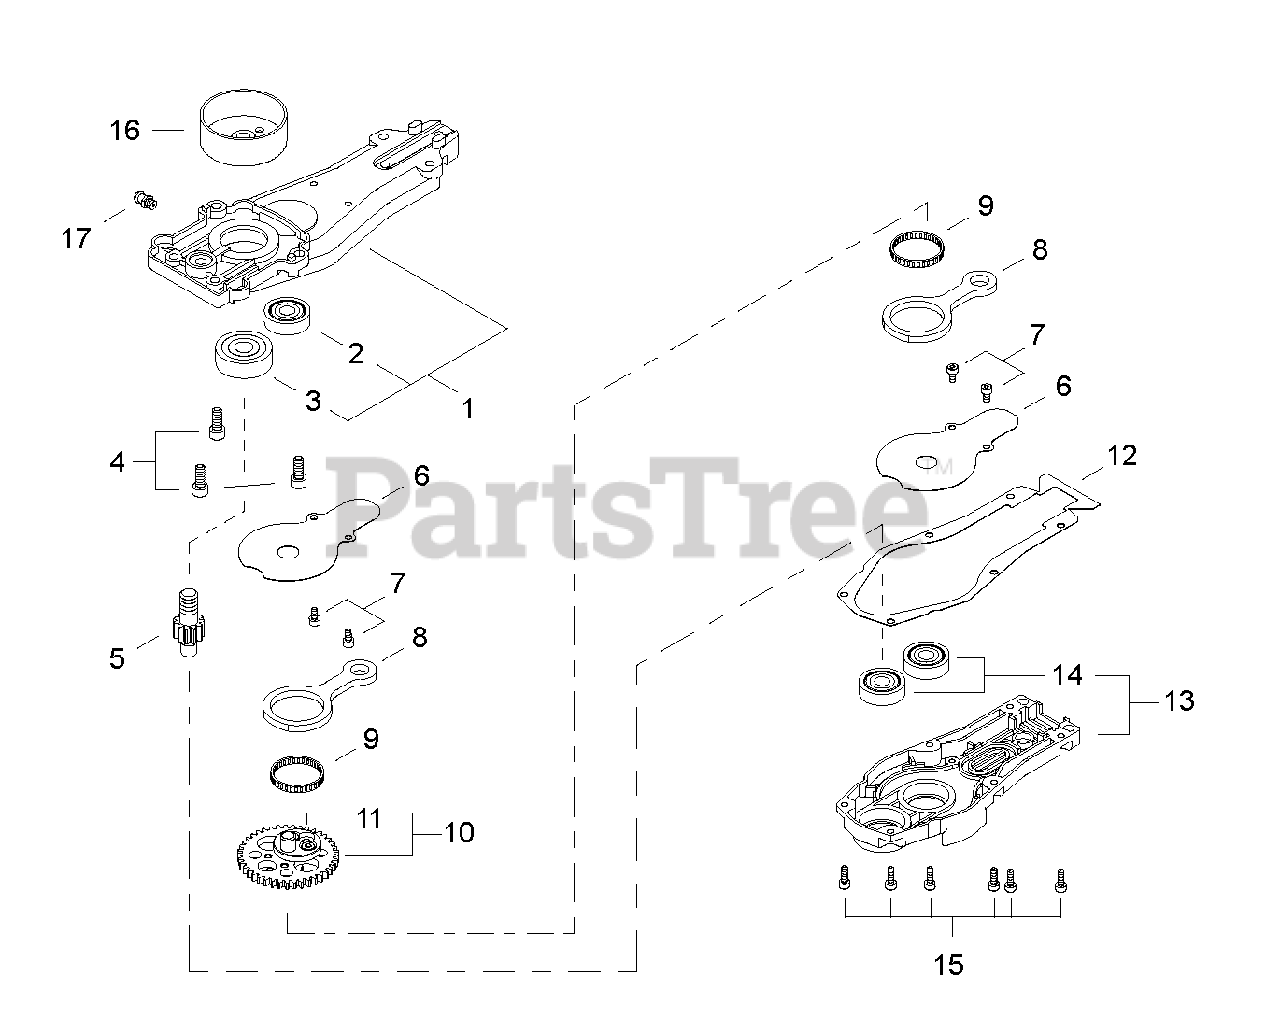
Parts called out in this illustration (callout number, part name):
1	GEAR CASE HOUSING ASSY
2	BEARING, BALL 6200ZZ
3	BEARING, BALL 6301 DDU
4	BOLT 6×16
5	PINION
6	PLATE, GEAR CASE
7	BOLT 4×8
8	CONROD
9	BEARING, NEEDLE 30
10	CAM GEAR ASSY
11	BOLT M5×6
12	GASKET, GEAR CASE
13	COVER ASSY, GEAR CASE
14	BEARING, BALL 6200ZZ
15	BOLT 4×14
16	DRUM, CLUTCH
17	FITTING, GREASE
